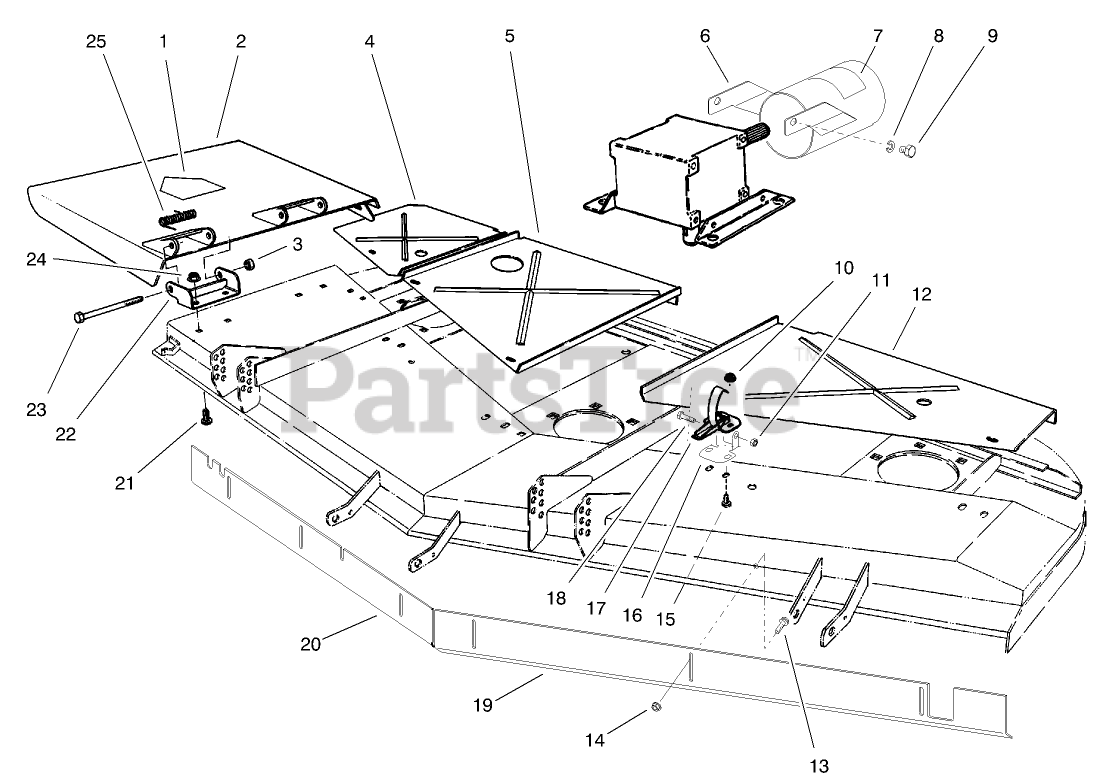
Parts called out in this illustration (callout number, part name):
1	DECAL-DANGER
2	Deflector (Incl. Ref. #1)
3	NUT-HEX
4	Cover-Deck R.H.
5	Cover-Deck Center
6	Guard-PTO Shaft
7	DECAL-DANGER
8	WASHER-LOCK
9	SCREW-HH
10	NUT-LOCK, FLANGE
11	NUT-LOCK, NI
12	Cover-Deck L.H.
13	SCREW-HHF
14	NUT-HF
15	SCREW-HWH
16	RETAINER-LATCH
17	CLAMP-SLOTTED
18	SCREW-HH
19	Baffle-Front LH
20	Baffle-Front RH
21	SCREW-CARR
22	Bracket-Hinge
23	SCREW-HH
24	NUT-HHF, WHIZ
25	SPRING
